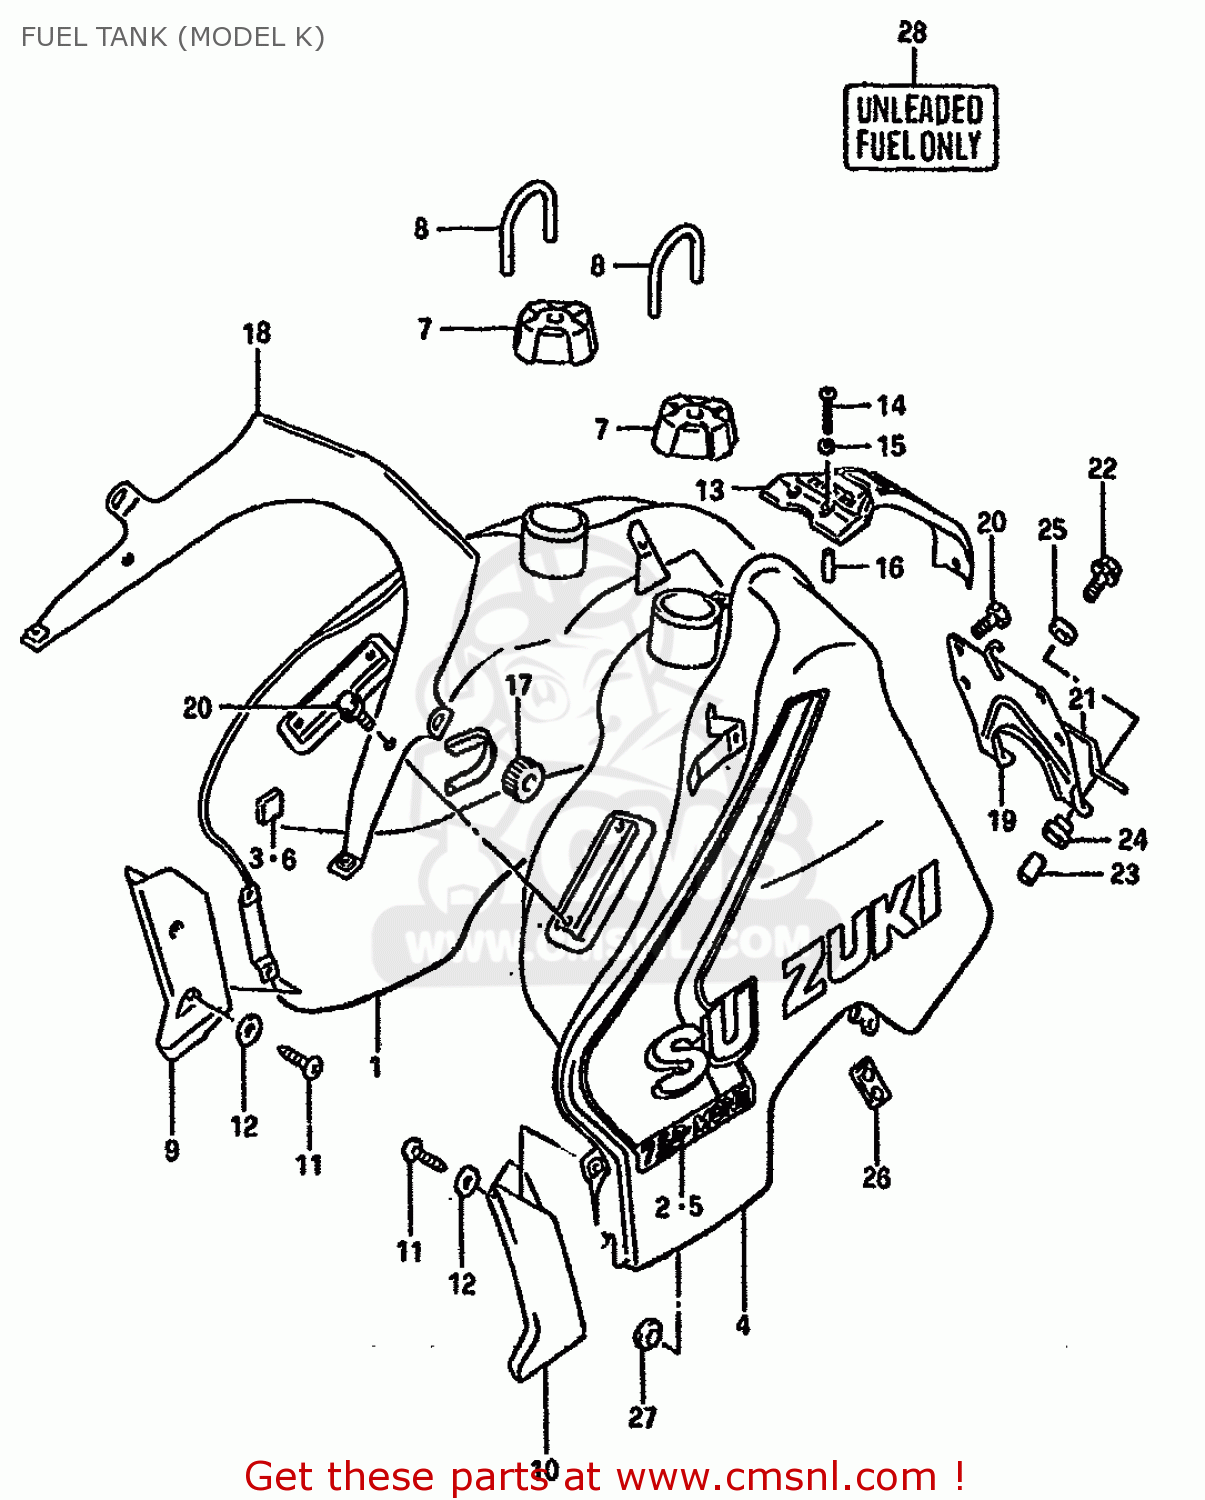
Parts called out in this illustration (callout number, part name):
1	TANK ASSY,FUEL RH (RED)
2	TAPE,FUEL TANK,R
3	CUSHION
4	TANK ASSY,FUEL LH (BLUE)
5	TAPE,FUEL TANK
6	CUSHION
7	CAP ASSY,FUEL TANK
8	HOSE
9	COVER,FUEL TANK FR,R
10	COVER,FUEL TANK FR,L
11	SCREW 6X12
12	WASHER
13	COVER,FUEL TANK CTR
14	SCREW (6X40)
15	WASHER
16	SPACER
17	CUSHION
18	BRACKET,FRONT
19	BRACKET,REAR
20	BOLT
21	BRACKET,SEAT FRONT HOOK
22	BOLT
23	SPACER
24	CUSHION
25	CUSHION
26	CUSHION
27	CUSHION
28	BOLT
29	WASHER (6.5X24X1.6)
30	SPACER
31	CUSHION
32	CUSHION
33	CUSHION
34	CUSHION
35	LABEL,FUEL CAUTION
